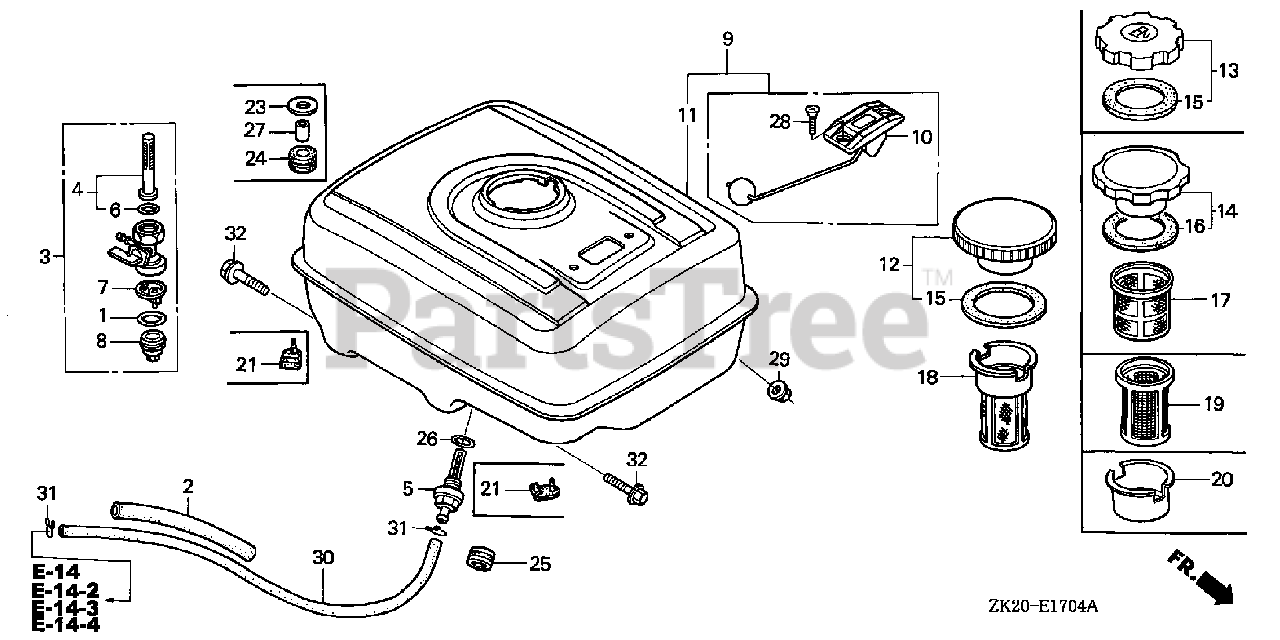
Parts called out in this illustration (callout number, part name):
2	RUBBER, SUPPORTER (107MM)
5	JOINT, FUEL TANK
11	TANK, FUEL *NH31* (MCKINLEY WHITE)
13	CAP, FUEL FILLER
15	GASKET, FUEL FILLER CAP
18	FILTER, FUEL
26	O-RING (13.5X1.5) (ARAI)
29	NUT, FLANGE (8MM)
30	BULK HOSE, FUEL (4.5X3000) (4.5X222)
31	CLIP, TUBE (B8)
32	BOLT, FLANGE (8X25)
